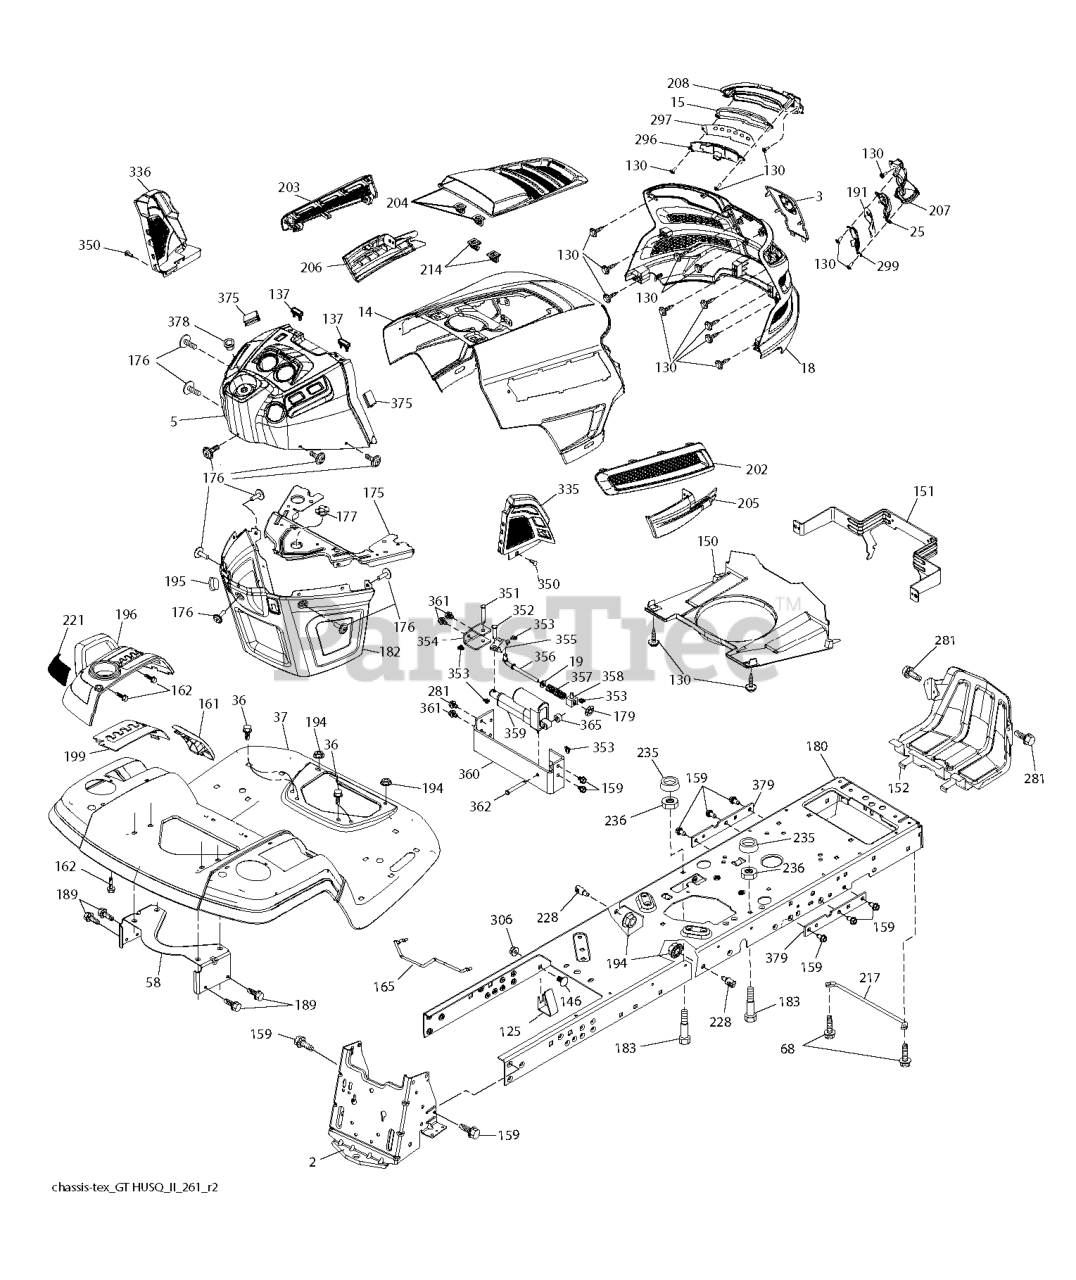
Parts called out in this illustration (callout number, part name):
2	DRAWBAR.STGT
3	APPLIQUE.SUBASM.GT.HUSQ.II
5	DASH.UPR.GT2.DUAL.RD.PT
5	DASH.UPR.GT2.DUAL.RD.PTO.MC
5	DASH.GT2.UPPER.RND.ELD.CP.498
14	HOOD.ASM.HUSQVARNA.GT.TEX.ORAN
15	LED LIGHT.LH
18	Grilles
18	GRILLE SUBASM.GT.II.LOW.HDLGHT
19	GSPH
19	Washers
25	LENS.RH
36	SCREW 5/16"
37	FENDER.PNT.TX.GT.CH/FW/DL.HUSQ
37	FENDER HUSQVARNA GT MS668 - HU
58	BRKT.SUPPORT.FNDR/TANK
68	Screws
68	SCR 5/16-18 X 1/2 SELFTAP ZN
125	CLIP.FUEL.LINE
130	Screws
130	SCREW.#10 X 0.750.BOS
137	BUMPER DASH
146	BOLT.RDHD.SHT.SQNK.3/8-16X5/8
150	AIR.DUCT.GTV.BLACK
151	BRACKET.PIVOT.HOOD.GT.HUSQ.II
152	SHIELD.BROWNING.PNT.GT.V2
159	SCREW, 3/8-16X3/4
161	FUEL WINDOW
161	CONSOLE.WINDOW.FUEL.HUSQ.GT
162	SCREW.HI-LO.CONSOLE
162	Screws
165	SUPPORT.TANK.REAR.B/TE
175	PLATE.PNT.CROSSMEMBER.HUSQ/PRE
176	SCREW.#10-24X5/8.RN.QU
177	BUSHING STEERING
180	CHASSIS.LT/GT.BOLTED
182	DASH.LOWER.COMMON.12V.ADAPTOR
183	BOLT.5/16-18X1-1/4 FULL THD
183	Screws
189	SCREW
191	INSERT INFLECT.RH
194	NUT LOCK HEX FLANGE 5/16-18
194	GSPW Nuts
195	PLUG.HOLE.DASH.LOWER.12V.BLK
196	SUBASM.CONSOLE.HUSQ.GT.DECKLFT
196	CONSOLE.ASM.DECKLIFT.HUSQGT.DL
199	PLATE.DECK.LIFT.HUSQVARNA.GT
202	VENT.SIDE.RH.GT.HUSQ.II.
203	VENT.SIDE.LH.GT.HUSQ.II.498
204	VENT.TOP.ASM.HUSQ.GT2
205	SIDE.TRIM.RH.GT.HUSQ.II
206	SIDE.TRIM.LH.GT.HUSQ.II.GRAY
207	BEZEL GT2 LED RH W/ LOWER.ATT
208	BEZEL GT2 LED LH W/ LOWER ATT
214	CLIP.RETAINER.TINNER.
217	ROD.PIVOT.HOOD
221	REFLECTOR.LH.TEX GT HU
228	STUD.FASTNER.W/ANTI-ROTATE
228	STUD.W/"D"ANTI-ROTATION
235	SPACER FENDER
235	Spacers
236	NUT.CENTERLOCK.5/16-
281	SCREW 3/8-16X1
296	LED LIGHT.LH
297	INSERT REFECT LH
299	LED LIGHT.RH
306	NUT LOCK FLG 3/8-16 UNC
335	COVER.LOWER.DASH.RH.BLACK
336	COVER-LH.LOWER.DASH.GT2.BLACK
350	CLIP.X-MAS.TREE
351	PIN.CLEVIS.375X2.125
352	PIN.CLEVIS.(.375 X 1.25)
353	CLIP RETAINER
354	SUPPORT.BELLCRANK
354	SUPPORT.DIFF.LOCK.BELLCRANK.
355	BELLCRANK.PIVOT.LOCK.DIFF
356	LINK.LOCK.DIFF
357	SPRING.COMPRESSION
358	GUIDE.SWIVEL
358	SWIVEL.GUIDE
359	ACTUATOR.ELECTRIC
360	BRACKET.ACUATOR
361	Screws
361	SCREW LT.3/8-46X5/8
362	PIN.CLEVIS.(.375 X 2.42)
365	SPACER.NYLON.75" X .4375
375	BUMPER CLIP-ON. DASH 1"
378	BUSHING FLANGE; PLASTIC
379	CHASSIS.PLATE.REINFORCEMNT.431
